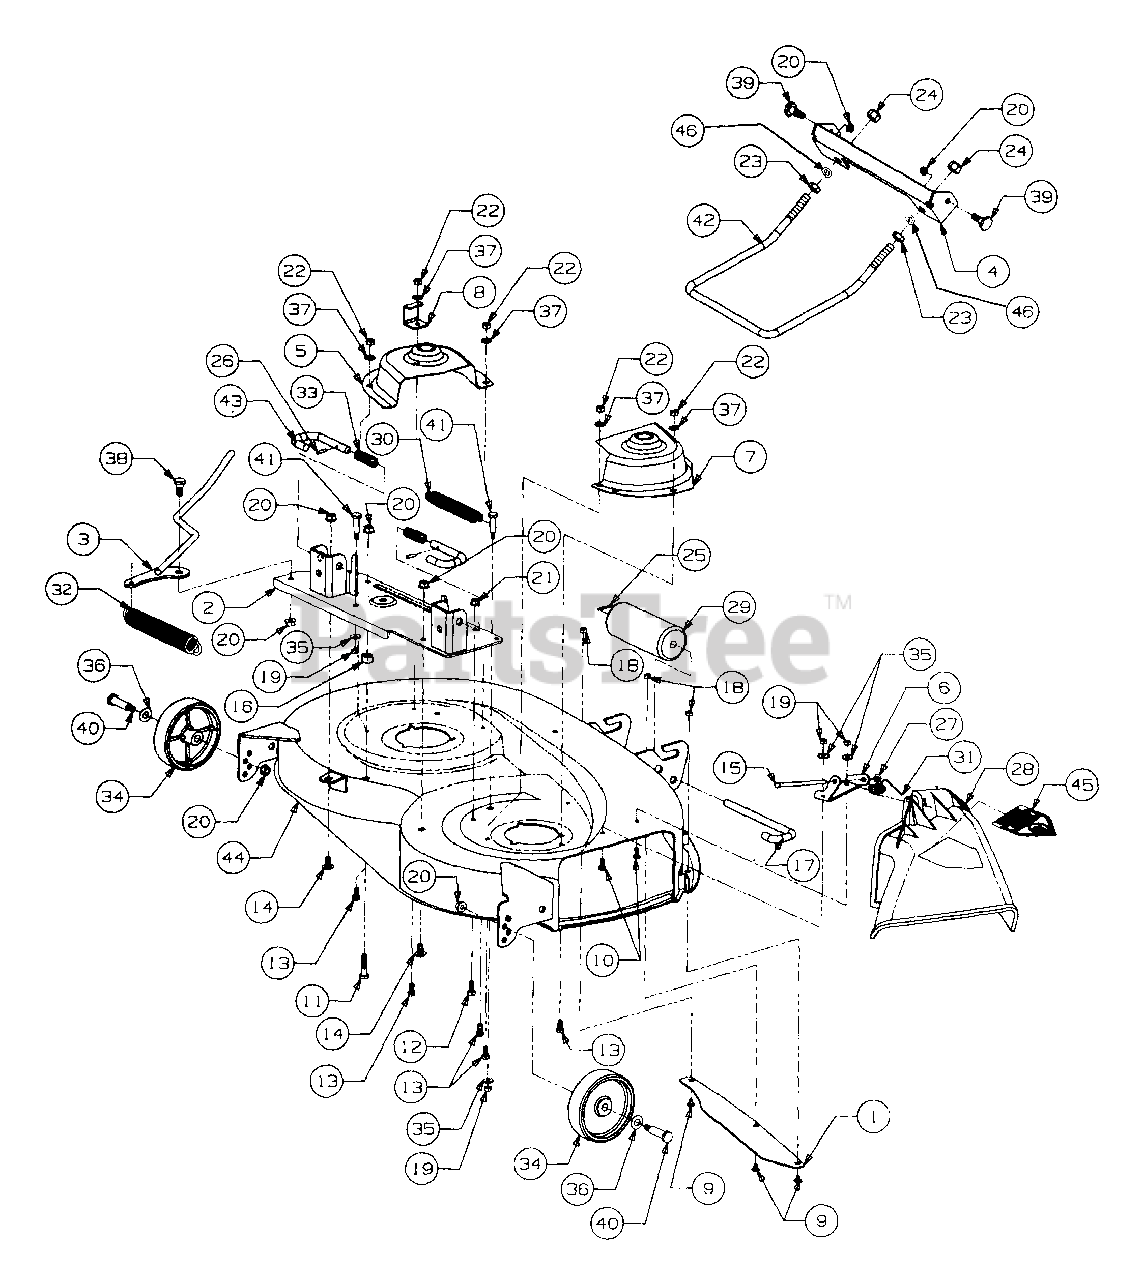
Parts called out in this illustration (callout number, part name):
1	Skirt, Extension
5	Cover, LH Belt
6	Bracket, Hinge Mounting
7	Cover, RH Belt
9	Bolt, Carriage, 1/4-20 x .50
10	Screw, Hex Cap, 1/4-20 x .62
11	Screw, Hex Cap 3/8-16 x 1.5 GR5
12	Screw, Hex Cap 5/16-18 x .75 GR5
13	Screw, Hex Cutting, 5/16-18 x .62
14	Bolt, Carriage, 3/8-16 x .75 GR5
15	Pin, Hinge, .25 Dia x 6.75 Lg
16	Spacer, .395 x .75 x .440
17	Pin, Roller, 1/2 Dia x 7.31 Lg
18	Nut, Hex Sems, 1/4-20
19	Nut, Hex, 1/4-20
20	Nut, Hex Flange Lock, 3/8-16
21	Nut, Hex Flange Lock, 5/16-18
22	Nut, Hex, 5/16-18 GR5
23	Nut, Hex Jam, 1/2-13 GR5
24	Nut, Hex Insert Lock, 1/2-13
25	Pin, Cotter, 1/8 x 1.0
26	Pin, Spirol Spring, 3/16 x .75
27	Cap, Speed Nut
28	Deflector Assy, Chute
30	Spring, Extension, .88 OD x 6.12
31	Spring, Torsion
32	Spring, Extension, 1.25 OD x 8.15
33	Spring, Compression
34	Wheel, Deck, 5 in. Dia
35	Washer, Bell, .265 x .75 x .062
36	Washer, Flat, .510 x 1.0 x .060
37	Washer, Flat, .34 x .68 x .062
38	Bolt, Shoulder, .498 Dia x .340 Lg
39	Bolt, Shoulder, .50 Dia x .434 Lg
40	Bolt, Shoulder, .498 Dia x 1.64 Lg
41	Bolt, Shoulder, .375 Dia x 1.16 Lg
42	Rod, Front Lift
43	Pin, Mower Support
44	Deck w/Graphics
44	Graphic, Rider Danger
44	Graphic, Man & Machine
44	Graphic, Assemble Chute
44	Graphic, Tension Lever
45	Graphic, Danger
46	Washer, Lock, 1/2
